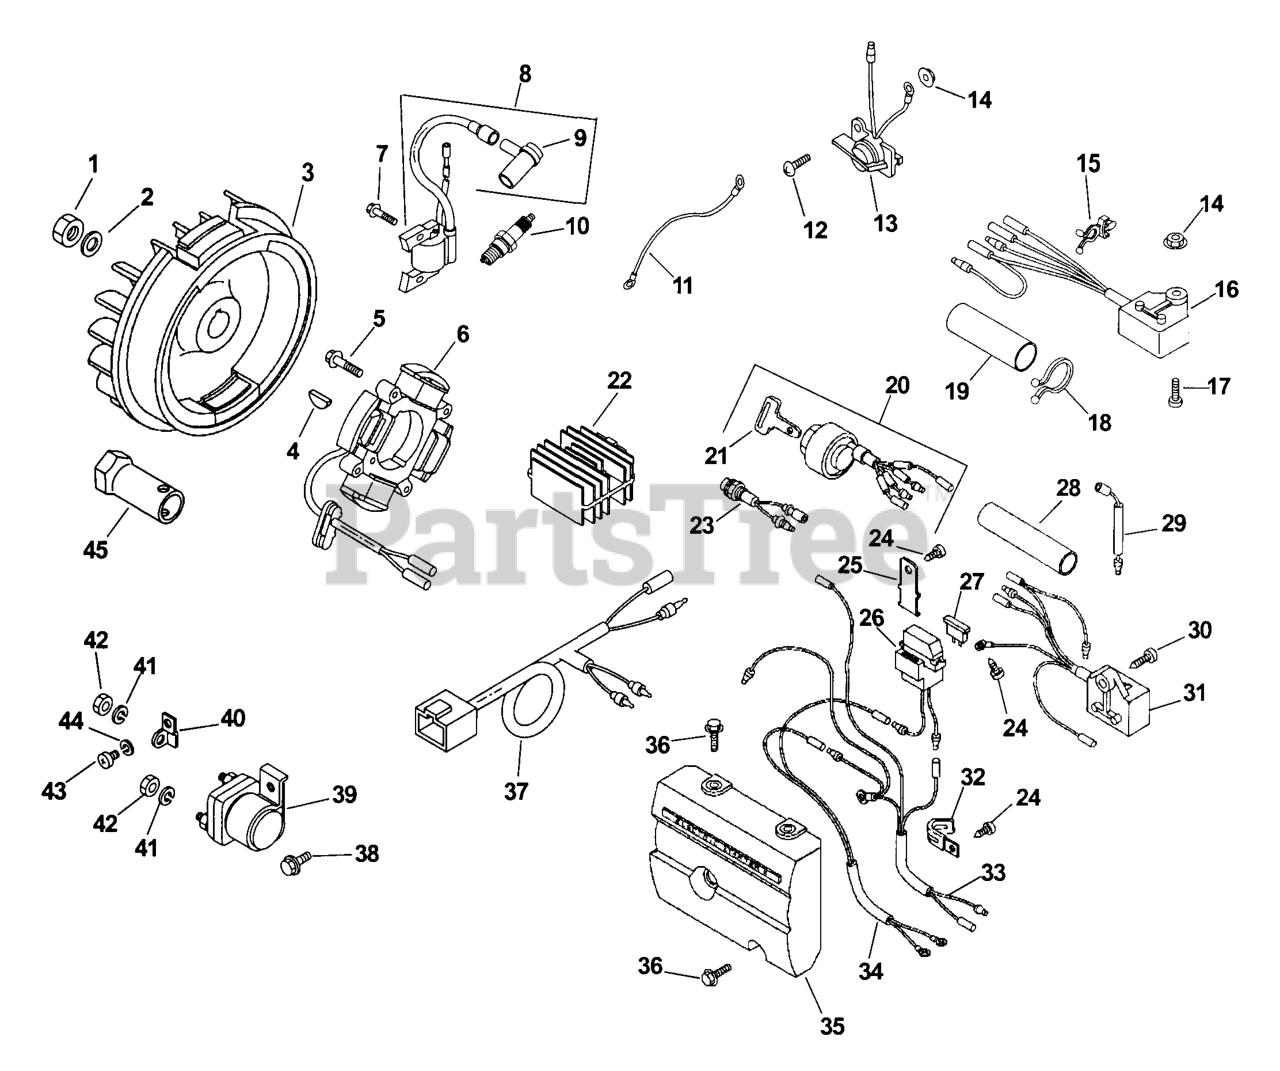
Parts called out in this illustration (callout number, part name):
1	NUT, FLYWHEEL
2	WASHER, F.W.
3	FLYWHEEL, MANUAL ST - DISCONTINUED
4	KEY, WOODRUFF
8	IGNITION MODULE KIT-USE 63 755 40-S
9	CAP ASSEMBLY
10	SPARK PLUG
11	LEAD,KILL
12	SCREW, STOP SWITCH
13	STOP SWITCH
14	NUT, STOP SWITCH
16	OIL SWITCH ASSEMBLY -USE 63 099 03-S
17	SCREW, PAN HEAD
18	CLAMP, WIRE
19	SLEEVE, WIRING
23	OIL LIGHT
